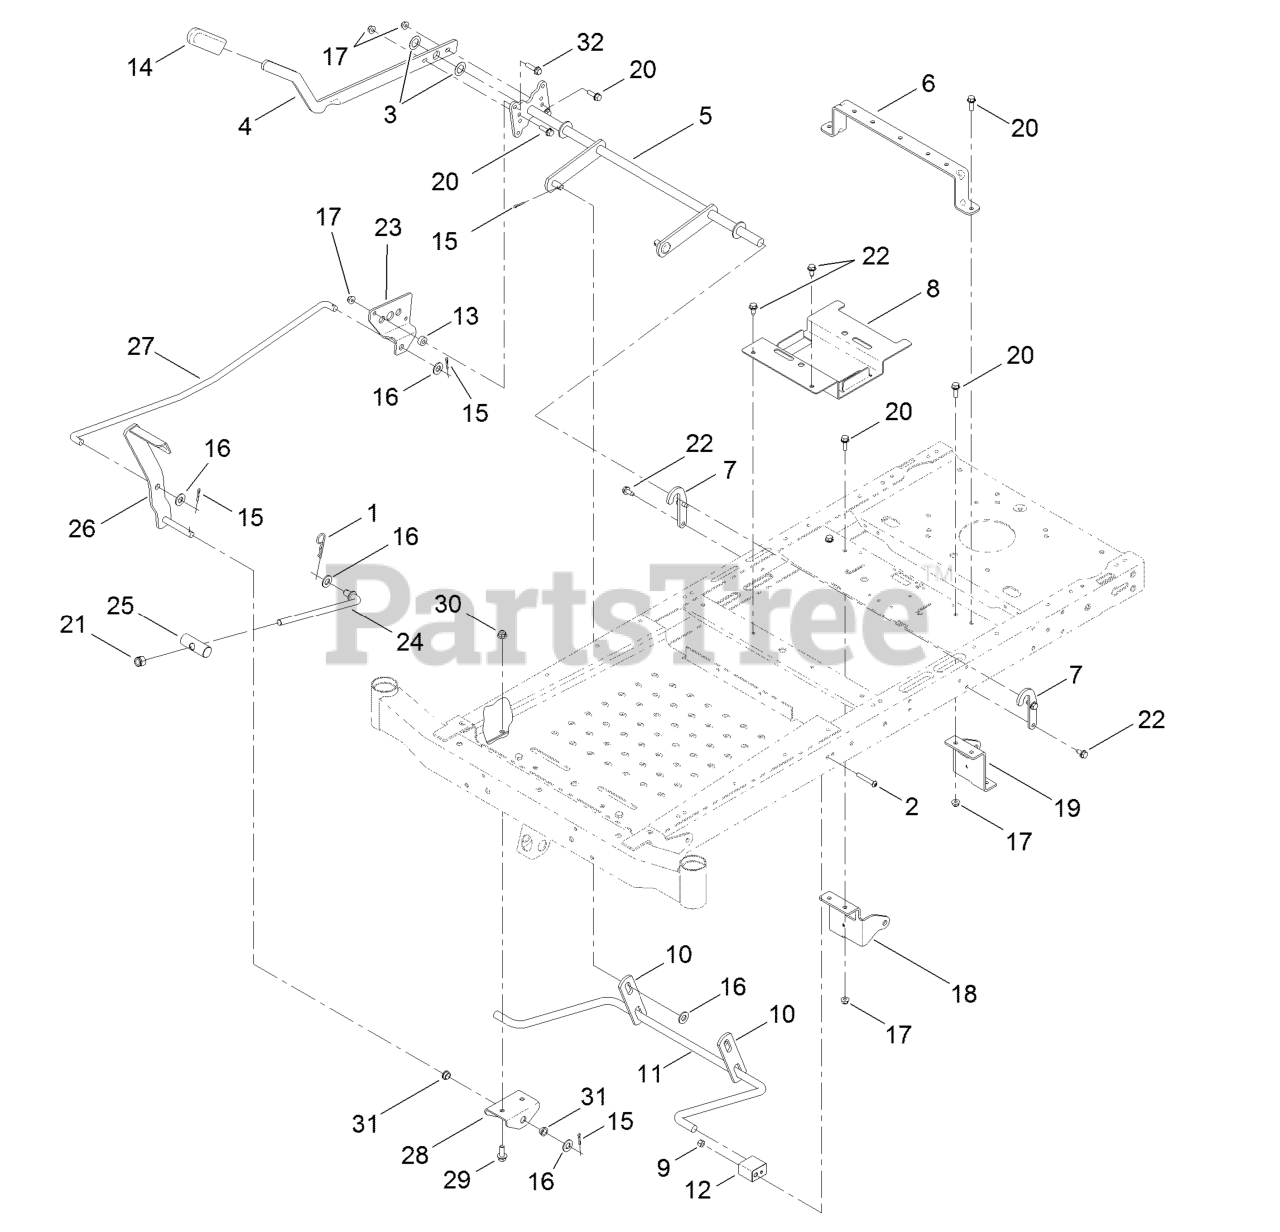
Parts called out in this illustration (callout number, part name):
1	PIN-COTTER
2	SCREW-HSBH
3	WASHER-THRUST
4	LEVER-LIFT
6	BRACE-SEAT, REAR
7	BRACKET-LIFT
8	BRACKET-BATTERY
9	NUT-LOCK, NI
10	LINK-LIFT
11	ARM-LIFT, REAR (WIDE)
12	BLOCK-PIVOT
14	GRIP-LEVER
15	PIN-COTTER
16	WASHER-FLAT
17	NUT-HF, NI
18	MOUNT-HYDRO, FRONT (RH)
20	SCREW-HHF
21	NUT-HEX
22	Screw-HWH 5/16-18 X 3/4 Tf
23	PLATE-FOOTLIFT
25	PIN-PIVOT
26	PEDAL ASM
27	ROD-FOOTLIFT
28	BRACKET-FOOTLIFT
29	SCREW-HHF 3/8-16 X 1
30	NUT-HF, NI
31	BUSHING-FLANGE
32	SCREW-HHF
